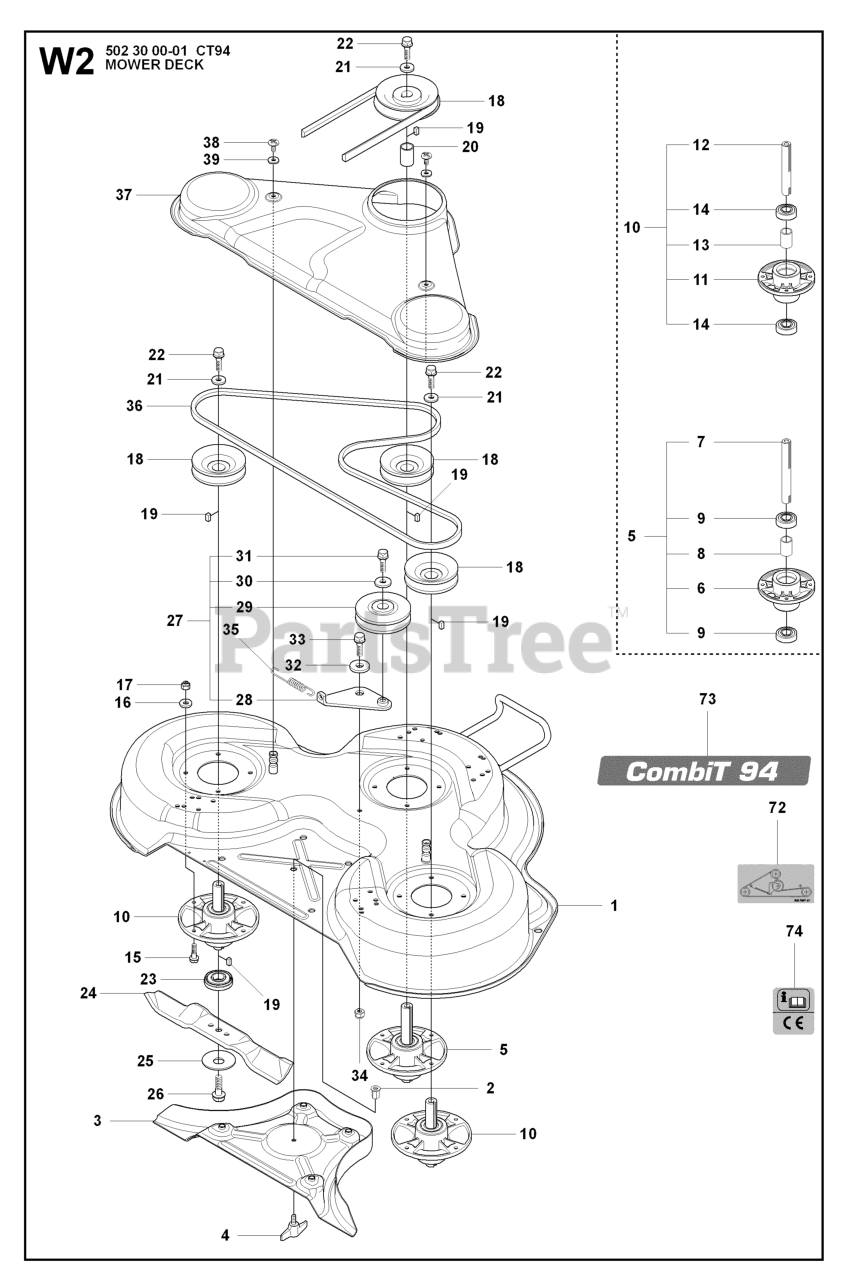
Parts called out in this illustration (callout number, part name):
1	DECK SHELL ASSY CT94 GREY
3	PLUG C93 & C94
9	BALL BEARING
14	BALL BEARING
16	WASHER BRB 8.4X17
17	LOCKNUT M8
27	BELT TENSIONER ASSY
28	BELT TENSIONING ARM
32	WASHER
34	LOCKNUT M8
37	BELT COVER C93 & C94 GREY
